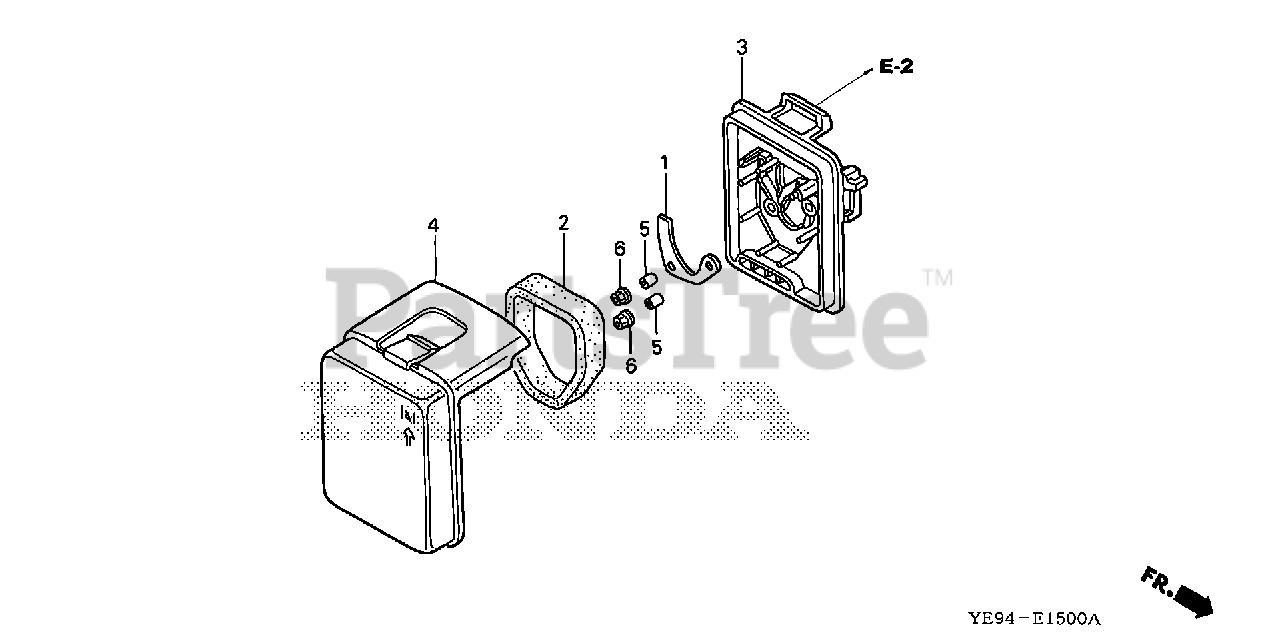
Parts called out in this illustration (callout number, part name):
1	PLATE, OIL TRAP
2	ELEMENT, AIR CLEANER
3	HOUSING, AIR CLEANER *R291R* (DARK POWER RED)
4	COVER, AIR CLEANER *R280* (POWER RED)
5	COLLAR, AIR CLEANER
6	NUT, FLANGE (5MM)
